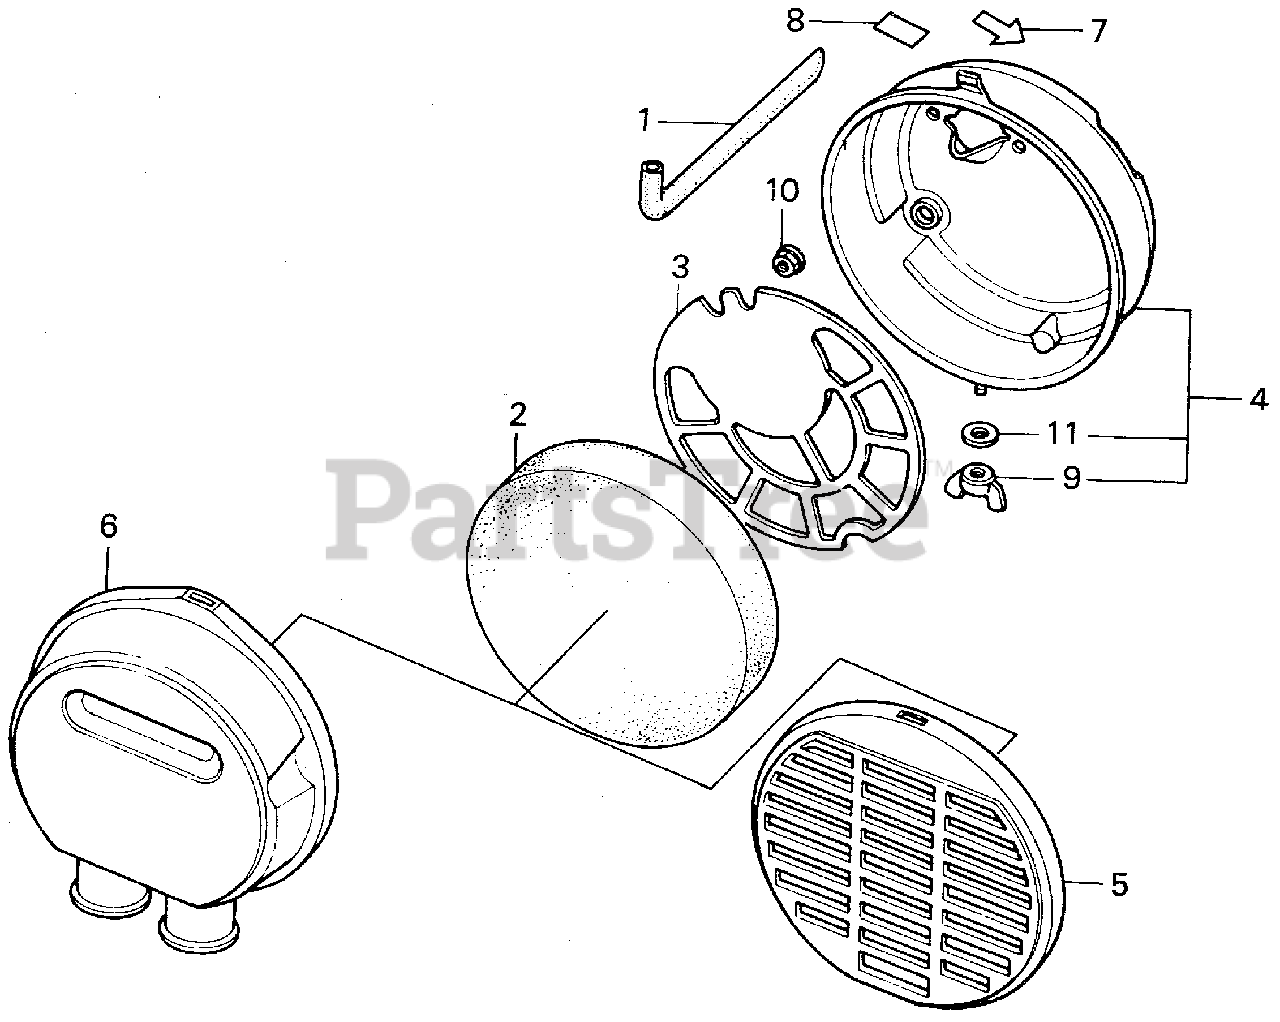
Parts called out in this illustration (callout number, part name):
1	TUBE, BREATHER
2	ELEMENT, AIR CLEANER
3	GRID, AIR CLEANER
4	HOUSING, AIR CLEANER
6	COVER, AIR CLEANER
7	MARK, CHOKE
8	MARK, CHOKE
9	WINGNUT, TOOL BOX SETTING
10	NUT, FLANGE (6MM)
11	WASHER, PLAIN (6MM)
